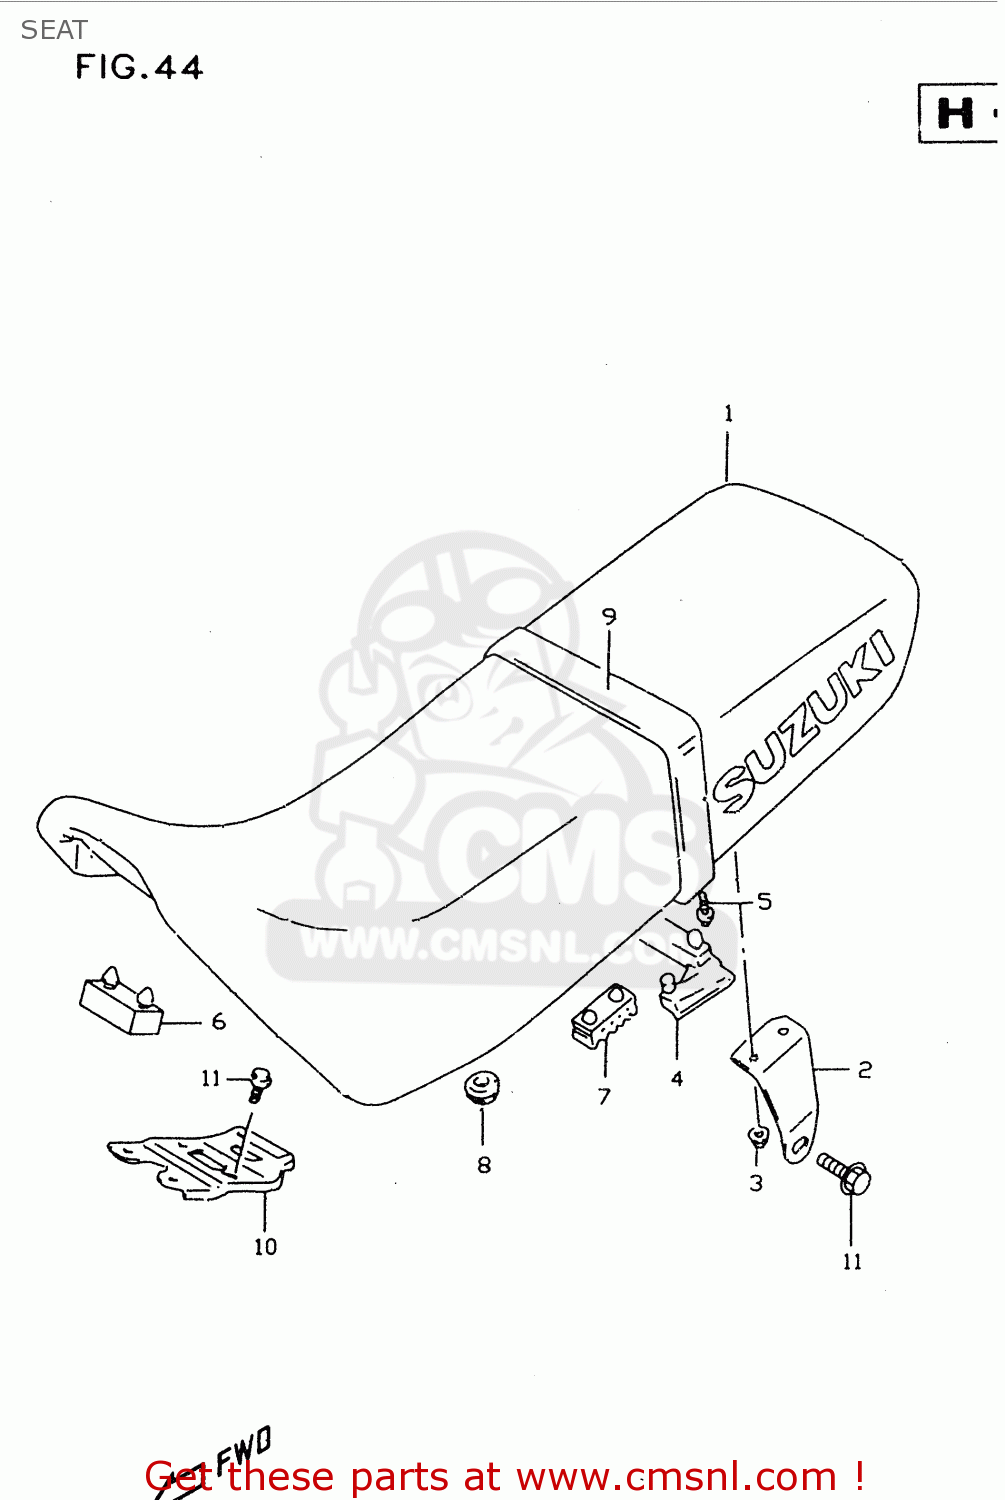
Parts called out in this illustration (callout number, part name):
1	SEAT SET
2	BRACKET,SEAT,R
3	NUT
4	CUSHION
5	BOLT
6	CUSHION
7	CUSHION,SEAT(40X20X15)
8	CUSHION
9	BAND ASSY,SEAT
10	PLATE,SEAT FR HOOK
11	BOLT
